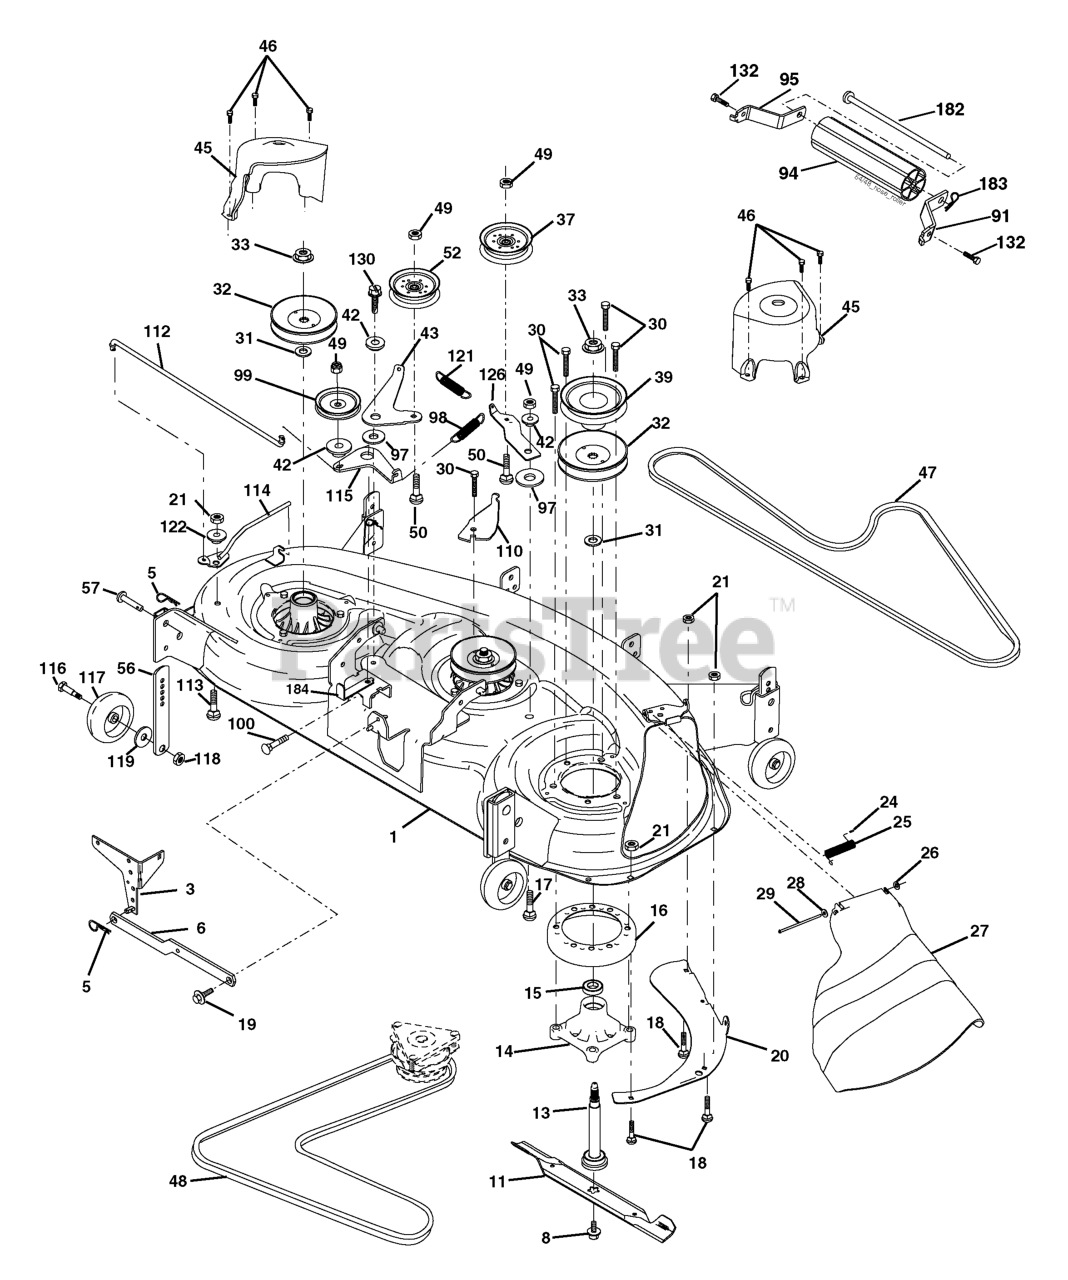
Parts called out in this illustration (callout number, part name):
1	DECK WELDMENT
3	BRACKET ASM.
5	RETAINER-SPRNG RB
6	BAR SWAY DECK
8	BOLT 7/16 ASM BLADE
11	BLADE.MULCH.48"
11	48" HI-LIFT BLADE
13	SHAFT ASM W/LOWER BEARING
14	HOUSING, MANDREL 48"
16	STRIPPER.MANDREL.ROUND.BLACK
17	BOLT
18	BOLT
19	BOLT SHD 5/16-18
20	BAFFLE, VORTEX MWR
21	LOCKNUT
24	CAP-SLEEVE LT
25	SPRING, TORSION
26	NUT PUSH M
27	DEFLECTOR SUBS TO 532 180655
28	Washer 11/32 x 5/8 x 16 Ga.
29	ROD.HINGE
30	SCREW, WASHER HEAD
31	WASHER.SPACER.MANDREL
32	PULLEY MANDREL
33	NUT, FLG TOPLOCK 9/16"
37	PULLEY.IDLER.FLAT
39	PULLEY.DRIVEN.DECK.48'
42	SPACER RETAINER
43	ARM, IDLER SECONDARY
45	COVER.MANDREL.DECK.48"
46	SCREW.1/4-20X5/8
47	V-BELT, 48"SECONDARY
48	V-BELT PRIMARY 48"
49	NUT LOCK FLG 3/8-16 UNC
50	BOLT.3/8-16X1.50
52	PULLEY.IDLER.FLAT.46.PR.DR.
56	BAR.ADJUST.WHEEL.ANTI.SCALP.BL
57	RIVET.PIN.HEAD.YELLOW.
91	BRKT.NOSEROLLER.RH.48"
94	NOSE ROLLER 48"
95	BRKT.NOSEROLLER.LH.48"
98	SPRING PRIMARY DRIVE
99	RP PULLEY.V.IDLER.
100	BOLT
110	ARM, SPRING SECONDARY
112	LEVER, TENSION RELIEF LINK
113	BOLT.CARR.SQNK.5/16-18UNC.X3/4
114	LEVER ASM, TENSION RELIEF
115	ARM, SPRING TENSION RELIEF
116	BOLT.SHOULDER.3/8-16X3-5/8.
117	RP WHEEL. GUAGE RALLY
118	LOCKNUT
119	WASHER.5/16.FLAT.STE.STD.
121	SPRING.DRIVE.SECONDARY.48".DEC
122	BUSHING, PIVOT TENSION RELIEF
126	ARM, IDLER PRIMARY DECK
130	SCREW 3/8-16X1
132	SCREW, 3/8-16X3/4
182	ROD.ROLLER.NOSE.NARROW.48"
183	SPRING RETAINER
184	KEEPER BELT IDLER PLATED
